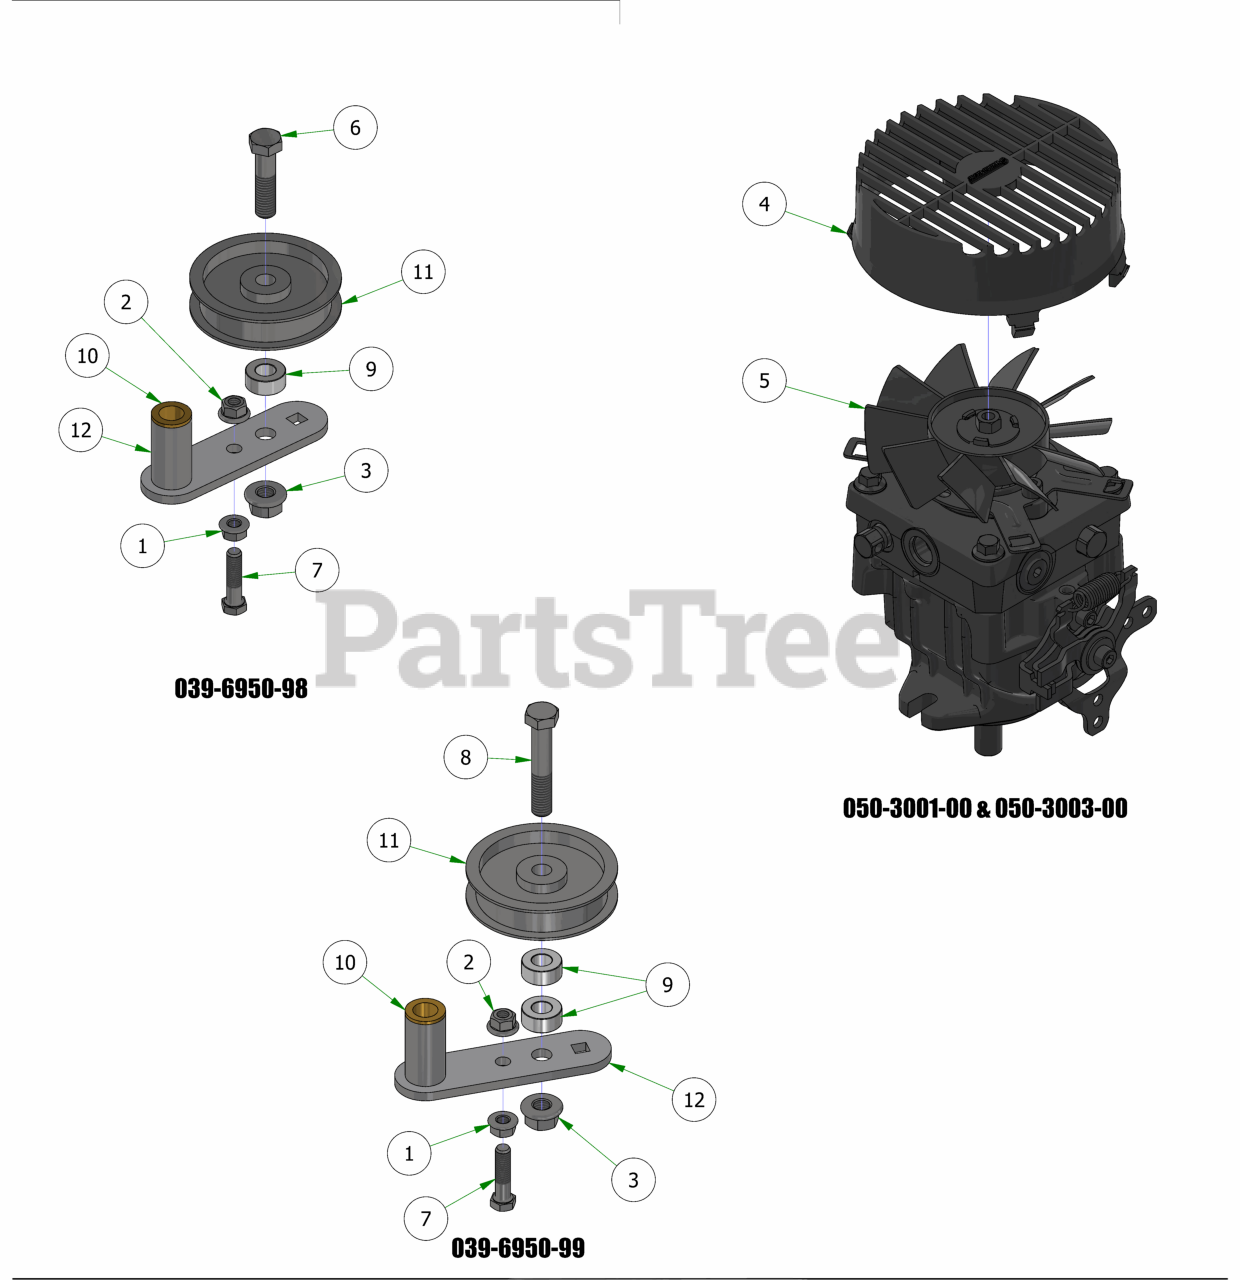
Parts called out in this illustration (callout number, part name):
1	3/8-16 HEX SERRATED FLANGE NUT HARD/ZINC
2	3/8-16 NYLON INSERT FLANGE LOCKNUT (GR.F) ZINC
3	1/2-13 NYLON INSERT FLANGE LOCKNUT ZINC
4	Fan Guard 6" - Fits Wheel
5	Hydro Fan - Light/Pup/Outlaw XP
6	1/2-13 X 2 HEX CAP SCREW (GR.8) ZINC YELLOW
7	3/8-16 X 1-1/2 HEX CAP SCREW (GR.5) ZINC
8	1/2-13 X 2-3/4 HEX CAP SCREW (GR.5) ZINC
9	1/2 Solid Shaft Collar (W/1 Set Screw) Zinc
10	.627 ID X .753 OD X .500 LGTH X 1.000 FLG OD X .094 FLG THICK FLANGED
11	3.25 Flat Idler Pulley
12	Renegade - Gas Pump Idler - Weldment
